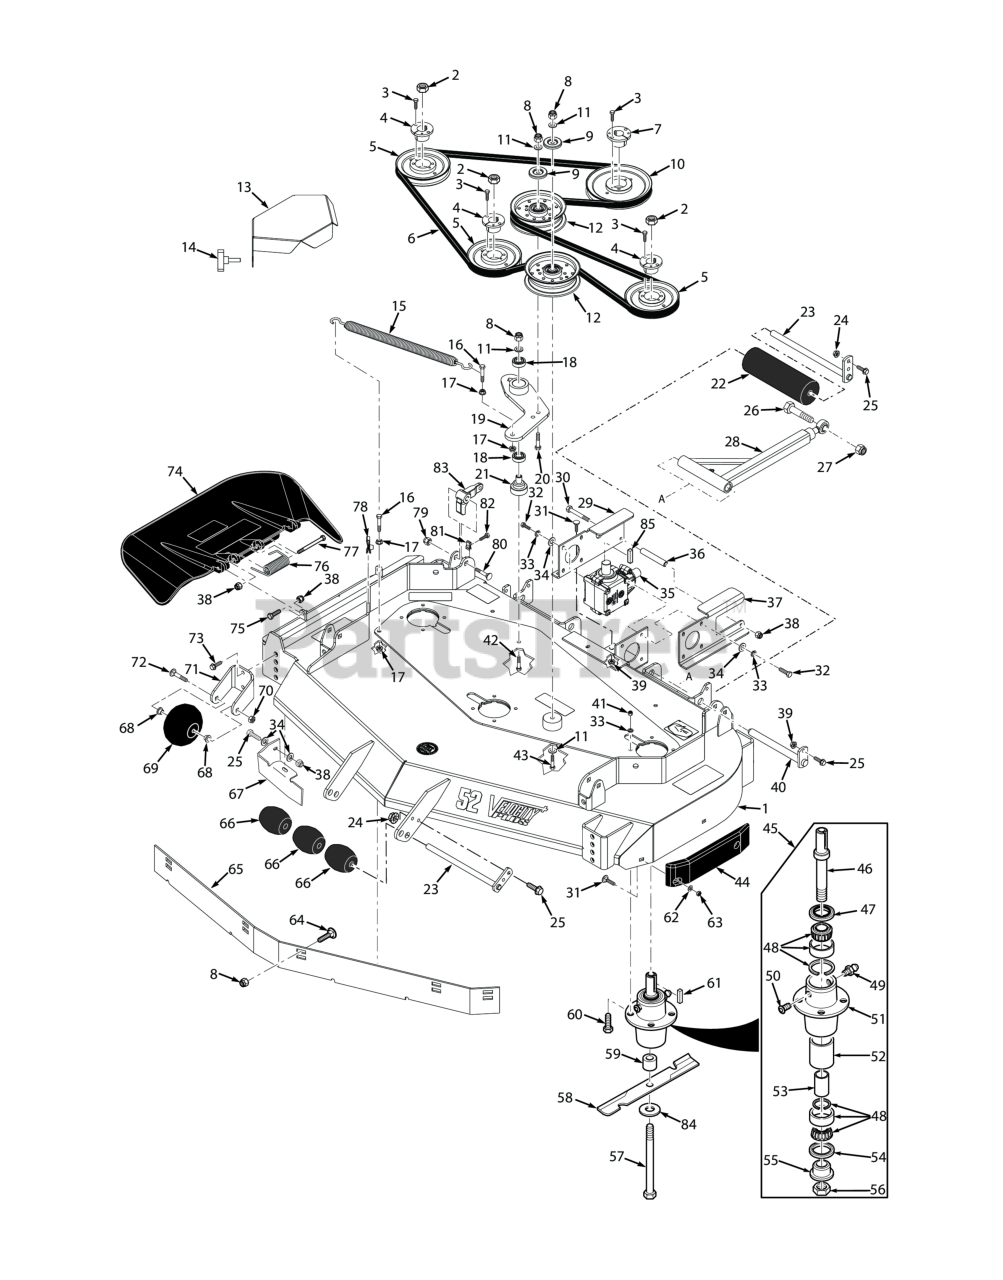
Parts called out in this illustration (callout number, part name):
1	Cutter Deck w/Decals - 52V
2	Hex Locknut, Elastic Stop, 3/8-16
3	Bolt, Hex Head 1/4-20 x 1" Grade 8 Black
4	Hub, Tapered 1-1/8" Bore
5	Pulley, 5.75 O.D. (Gasoline Engines)
6	Belt, Cutter Deck Drive
7	TAPERED HUB, 1.00" BORE
8	HEX NUT, ELASTIC STOP LOCK, 3/8-16
9	Quick Pin, 5/16" Dia.
10	Pulley, 6.95" O.D. - 72"
11	Flatwasher, 3/8 (.391 x .938 x .105 HD) Grade 8
12	Idler Pulley, Belt Clutch
13	Belt Cover LH
14	Knob, w/stud 3/8-16 x 1-1/4"
15	Spring, Cutter Deck
16	Bolt, Hex Head 3/8-16 x 1-1/2" Grade 8 Black
17	NUT, 3/8-16 SERRATED FLANGE HEX HEAD
18	BEARINGS, BALL, NEUTRAL RETURN
19	Idler Arm, Cutter Deck
20	Capscrew, Hex Head 3/8-16 x 2.75"
21	Pivot, Idler - Short
22	Wheel, Anti-ScalpRelief Fitting, Tapered Spindle
23	Shaft Weldment, Guide Roller
24	Nut, Flange Head Elastic Stop 5/16-18
25	Bolt, Heax Head 5/16-18 x 1" (48V / 52V)
26	BOLT, HEX HEAD 5/8-11 X 4-1/2"
27	HEX LOCKNUT, ELASTIC STOP, 5/8-11
28	Push Arm (Includes 64,60,62)
29	Mounting Plate
30	Bolt, 5/16-18 x 4-3/4" Hex Head
31	Bolt, 5/16-18 x .75 RHSN Carriage
32	Bolt, Heax Head 5/16-18 x 1" (48V / 52V)
33	Lockwasher, 5/16 (.317 x .586 x .078) Helical Spring
34	Flatwasher, 5/16-.375 x .875 x .083 (35BV & 37BV-EFI)
35	Gearbox Assembly, Deck Drive
36	Spacer, Gearbox Mount
37	Mounting Plate
38	HEX NUT, ELASTIC STOP LOCK, 5/16-18
39	Nut, Serrated Flange 5/16-18 (Right Front Engine Mounting, Briggs and Kohler Only)
40	Shaft Weldment, Pusharm
41	Lock Nut, 5/16-18 Elastic Stop Grade 8
42	Bolt, Hex Head 3/8-16 x 3" - 52"
43	Capscrew, Hex Head 3/8-16 x 3-3/4"
44	Pad, Deck Wear
45	Cutter Spindle Assembly
46	Spindle Shaft, Tapered Brng
47	SEAL, 2.00 O.D. X 1.50 BORE
48	Tapered Bearing Set (Two Bearings W/Race)
49	GREASE FITTING, STR. 1/4-28 SELF TAP.
50	RELIEF FITTING, TAPERED BEARING SPINDLE
51	Housing, Spindle
52	Spacer, Outside, Cutter Spindle
53	SLEEVE, CUTTER SPINDLE
54	Seal, 2.00" O.D. x 1.625" Bore
55	SPINDLE BUSHING, BOTTOM
56	Nut , Spec ial 1 -1/ 1 6 - 1 8
57	BOLT, HEX HEAD, 5/8-11 X 9-1/2 GR.5
58	Cutter Blade, 18" (52V)
59	Spacer, Spindle Bottom
60	Bolt, Hex Head 5/16-18 x 1-3/4" Grade 8
61	Key, 1/4 x 1/4 x 2.0"
62	Flatwasher, 5/16-.344 x .688 x .065 (48V / 52V)
63	Nut, Center Lock, 5/16-18(32)
64	Carriage Bolt, 3/8-16 x 1.0"
65	Baffle Custom-Cut, 52V (7-Position)
66	Wheel, Anti-Scalp
67	Turbo Baffle - 48V / 52V
68	Bushing, .376" I.D. Oilite
69	Bolt, Carriage 3/8-16 x 4"
70	Bolt, Hex Head 3/8-16 x 1" Ser. Flg.
71	Bracket, Anti-Scalp Wheel
72	Bolt, Hex Head 3/8-16 x 3-1/2"
73	Capscrew, 3/8-16 x 1.0" Serrated Flange Hex Hd
74	Discharge Chute Assembly - 52V
75	Bolt, Hex Head 5/16-18 x 1-1/2" - Front
76	Spring, Discharge Chute
77	Bolt, 5/16-18 x 4-3/4" Hex Head
78	U-Nut, 3/8-16
79	HEX LOCKNUT, ELASTIC STOP, 7/16-14
80	Bolt, Carriage 7/16-14 x 2-1/4"
81	U-Nut, 3/8-16 (short)
82	Bolt, Hex Head 3/8-16 x 2" Special Lock
83	Lever, Deck Level
84	Flatwasher, 5/8-.688 x 1-3/4 x .134 HD
85	Key, 1/4 x 1/4 x 1.25" Pulley Mtg.
